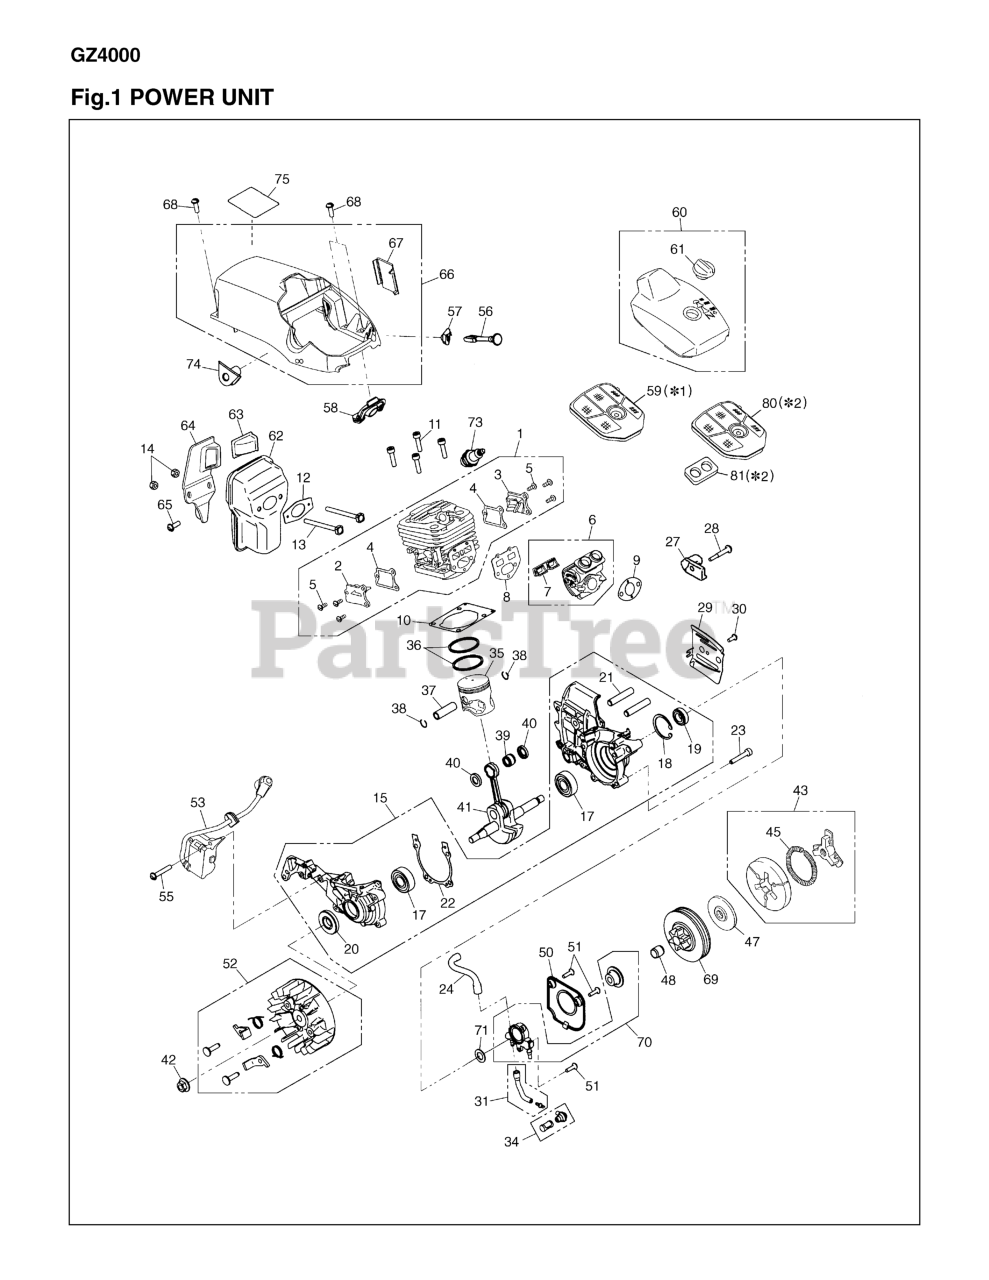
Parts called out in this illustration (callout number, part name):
1	CYLINDER ASSY
2	TR COVER MAG
3	TR COVER PTO
4	GASKET
6	INSULATOR
7	SEAL
8	GASKET
9	GASKET
10	GASKET, CYLINDER
11	BOLT (RPLS 2850-14220)
12	GASKET, MUFFLER
13	BOLT, MUFFLER
14	NUT, MUFFLER (RPLS 3356-15230
15	CRANKCASE ASSY
17	BEARING
18	RING, SNAP, M32 x 1.2
19	SEAL, OIL (RPLS 1100-21210)
20	SEAL
21	STUD (RPLS 0205-50825)
22	GASKET, CASE
23	BOLT
24	PIPE
27	CATCHER
29	PLATE (A)
31	PIPE IN COMP.
34	FILTER COMP
35	PISTON
36	RING
37	PIN
38	RING, SNAP
39	BEARING
40	WASHER
41	SHAFT COMP
43	CLUTCH ASSEMBLY
45	SPRING
47	PLATE
48	BEARING
50	COVER, PUMP
51	SCREW
52	ROTOR COMP
53	COIL ASSY
55	SCREW
56	ROD, CHOKE
57	GROMMET, CHOKE
58	GROMMET, THROTTLE
59	CLEANER ASSY (UNTIL 2009 MODEL)
60	COVER COMP
61	KNOB (RPLS 3356-83322)
62	MUFFLER
63	ARRESTER, SPARK
64	STAY
65	SCREW (REPLACES 2616-24320)
66	COVER COMP
68	SCREW
69	DRUM, CLUTCH
70	OIL PUMP SET(RPLS T210055110)
71	THRUST WASHER
74	GROMMET
75	LABEL
80	CLEANER (FROM 2010 MODEL)
81	CLEANER COMP (FROM 2010 MODEL)
NI	PIN
NI	PIPE
NI	PIPE IN
NI	JOINT
NI	SHOE
NI	BOSS
NI	OIL PUMP
NI	WORM
